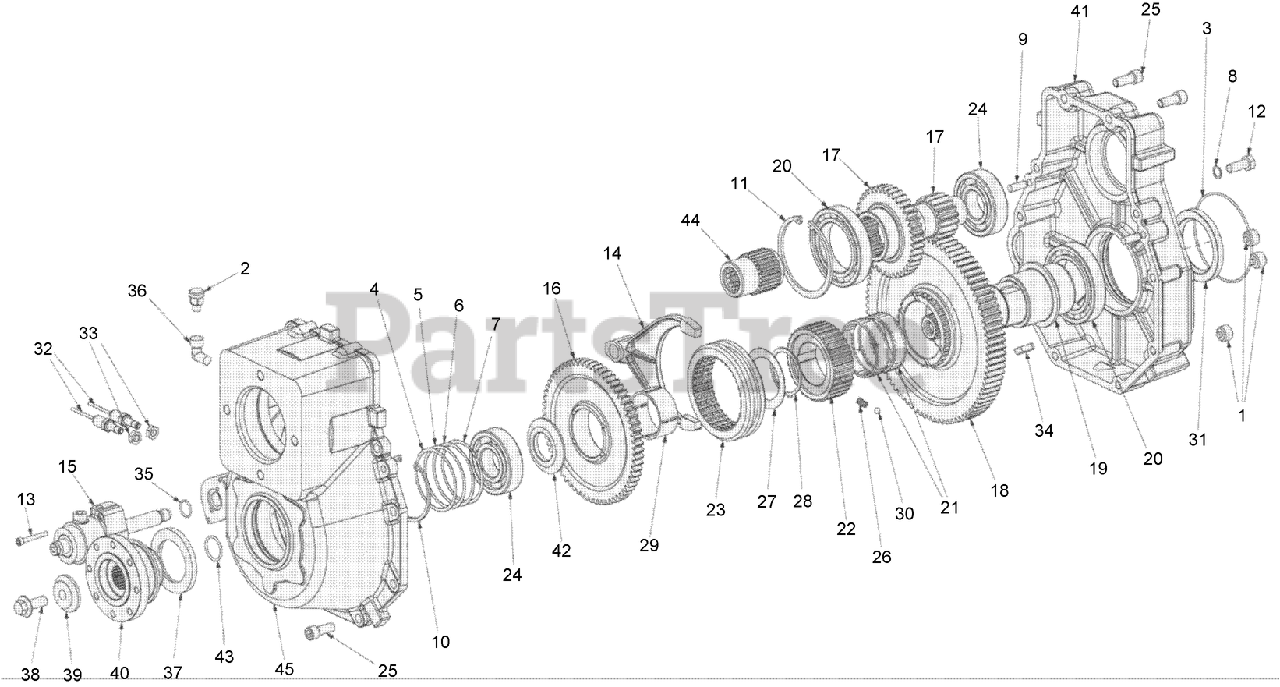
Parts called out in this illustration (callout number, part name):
3	O-RING
8	Washer
10	RING-Internal Retaining
11	RING-SNAP
14	FORK-Gearbox
15	CYLINDER-Gearbox
16	GEAR-Drive, 2nd Run
17	Gear-Drive
18	GEAR-Drive, 1st Run
19	SHAFT-DRIVE
20	Bearing-Ball
21	CAGE-Needle Bearing
22	HUB-Selector
23	COLLAR-Shift
24	Bearing
26	SPRING-Selector
27	Shim
28	RING-SNAP
29	BEARING-NEEDLE
30	SPHERE-5/16 (Gear Selection)
32	SENSOR-Gear Selector
35	O-RING
36	ELBOW-90 Deg
39	WASHER-Pinion
40	FLANGE-PTO
41	Housing-Gear
42	SHIM-Gear
43	O-RING
44	SLEEVE-Motor
45	COVER-Gear
